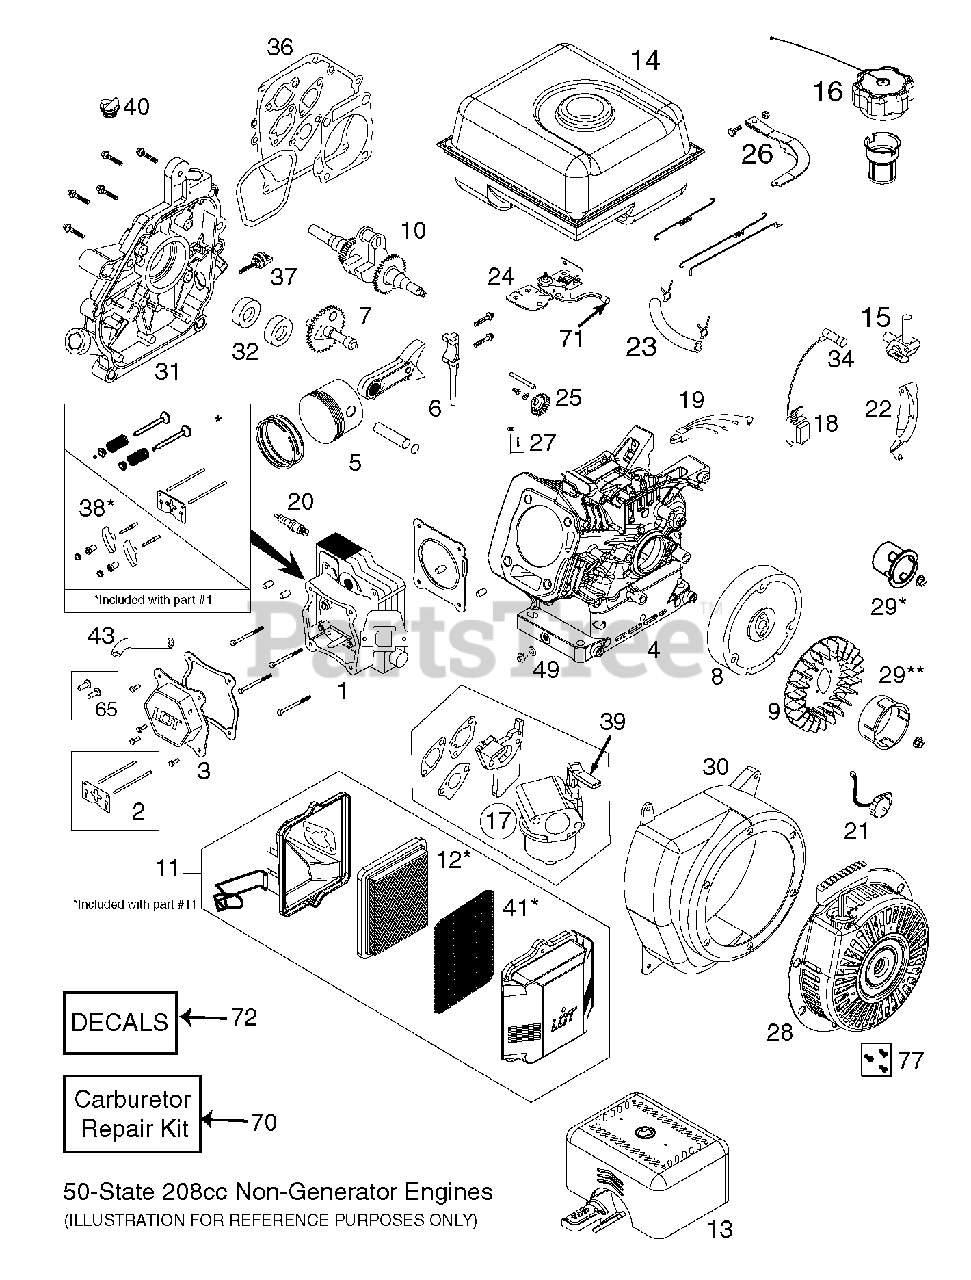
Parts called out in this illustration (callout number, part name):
1	CYLINDR.HEAD.SRV.KIT
2	KIT.PUSH.ROD.SRV(SK208-1001)
3	VALVE COVER ASSEMBLY
4	CYLINDER.GEN2.NO.LOW.OIL.SENSO
5	KIT.PISTON.SRV(SK208-1400)
6	KIT.CONNECT.ROD.SRV(SK208-1500
7	KIT.CAMSHAFT.SRV(SK208-1600)
8	FLYWHL.ASSY.MANUL.SK2081700
9	KIT.COOLNG.FAN.SERV(SK208-4000
10	CRANKSHAFT.KEYED.#14.LCT.208CC
11	KIT.AIRFLTR.ASY.SRV(SK208-2002
12	FILTER.ASSEM.PANEL.LCT.208CC
13	50 STATE MUFFLER SERV KIT
14	FUEL.TANK.2.7L.50STATE.LCT.208
15	FUEL.PETCOCK.1/4".LCT
16	CAP.FUEL.50STATE.W/CHAIN.LCT.
17	KIT.CARBURETOR.SERV(SK20-2401)
18	IGNITION.COIL.CDI.STOP.N.CONTR
20	SPARK.PLUG(2083810)
21	KIT.ENGINE.ON/OFF.LCT.208CC
22	SHIELD.FLYWHEEL.GEN2.LCT.208CC
23	FUEL HOSE KIT
24	CONTROL.THROTTLE.S-N-C.LCT.
25	GOVENOR.GEARS ASM(SK2082900)
26	KIT.GOVERNOR.ARM(SUMMER ENG)
27	KIT.GOVERNOR.CRANK(SK208-3100)
28	RECOIL.STARTER.ROUND.BLACK
29	START.CUP.NON-SLOTTED
30	HOUSING.BLOWER.BLACK.LCT.208CC
31	COVER.CRANKCASE.LCT.HIGH.OIL.F
32	SEAL KIT (2 PCS)
34	SPARK.PLUG.BOOT(SK2083800)
36	GASKET.KIT.208CC(SK2084300.1)
37	DIPSTICK SMALL
38	ROCKER ARM KIT
39	CHOKE LEVER.CARB.LCT.208CC
40	NON REMOVABLE PLUG
41	FOAM.PRE.FILTER.LCT.208CC
43	TUBE.BREATHER.LCT.208
49	KIT.OIL.DRAIN.PLUG(SK2089911
65	TAPPET.KIT.LCT.208CC
70	CARB.REPAIR.KIT.LCT.SK9900.1
71	KNOB.SPEED.CONTROL.RED.LCT.
77	BOLT.KIT.RECOIL.LCT.ALL.ENGINE
